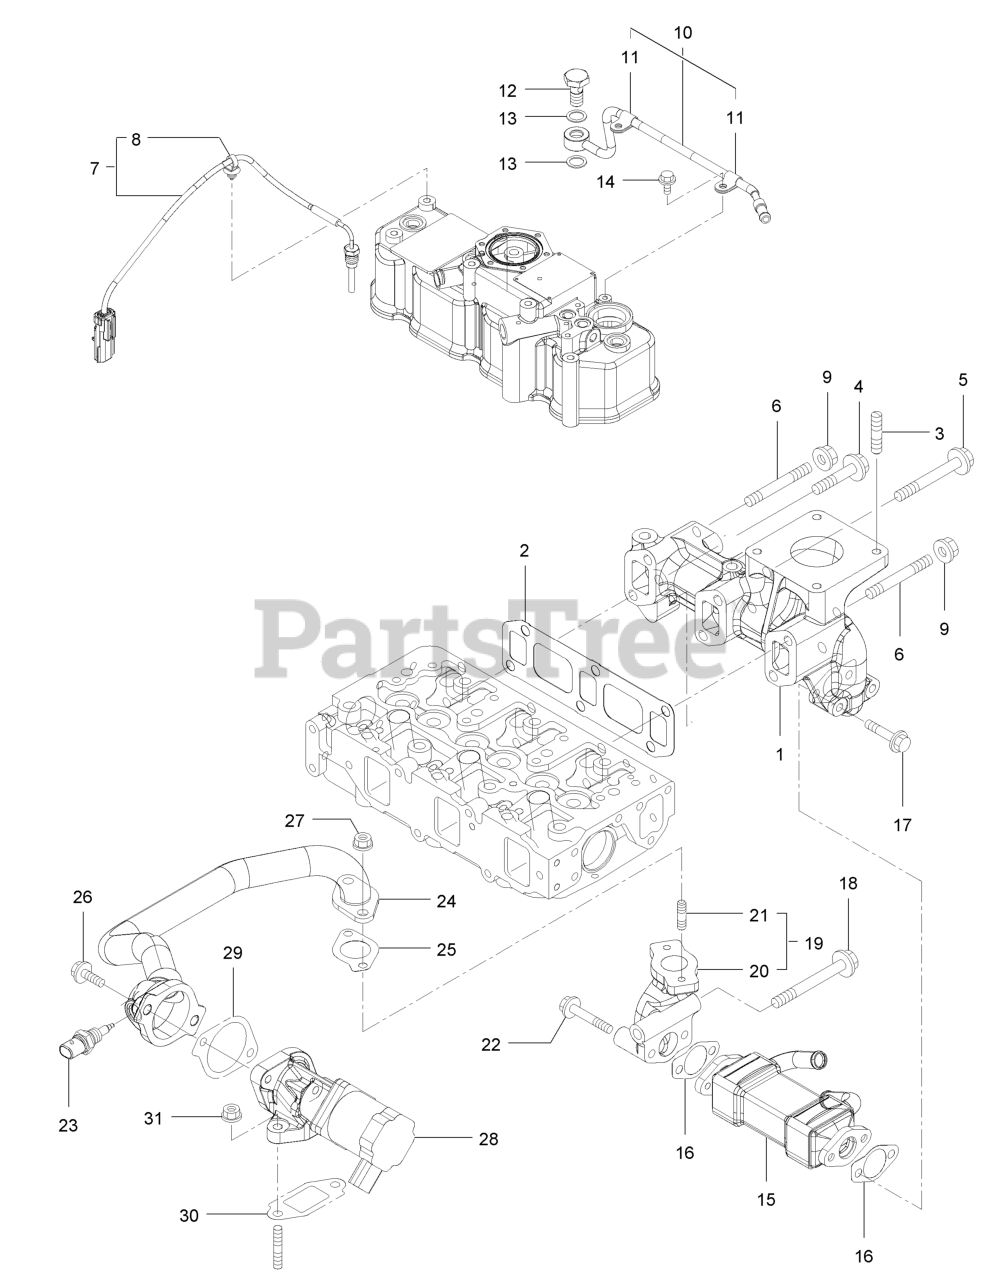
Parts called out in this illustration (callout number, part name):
1	Manifold-Exhaust
2	Gasket-Manifold, Exhaust
7	Sensor-Temp, Exhaust
8	Band-Clip
10	Exhaust Pipe ASM
12	Bolt-Joint, Pipe
15	Cooler-E G R
16	Gasket-Cooler, E G R
19	E G R Pipe ASM
20	Pipe-Out, E G R
23	Sensor-Gas Temp, E G R
24	E G R Pipe ASM
28	Valve-E G R
29	Gasket-Intake Valve, E G R
30	Gasket-Out Valve, E G R
